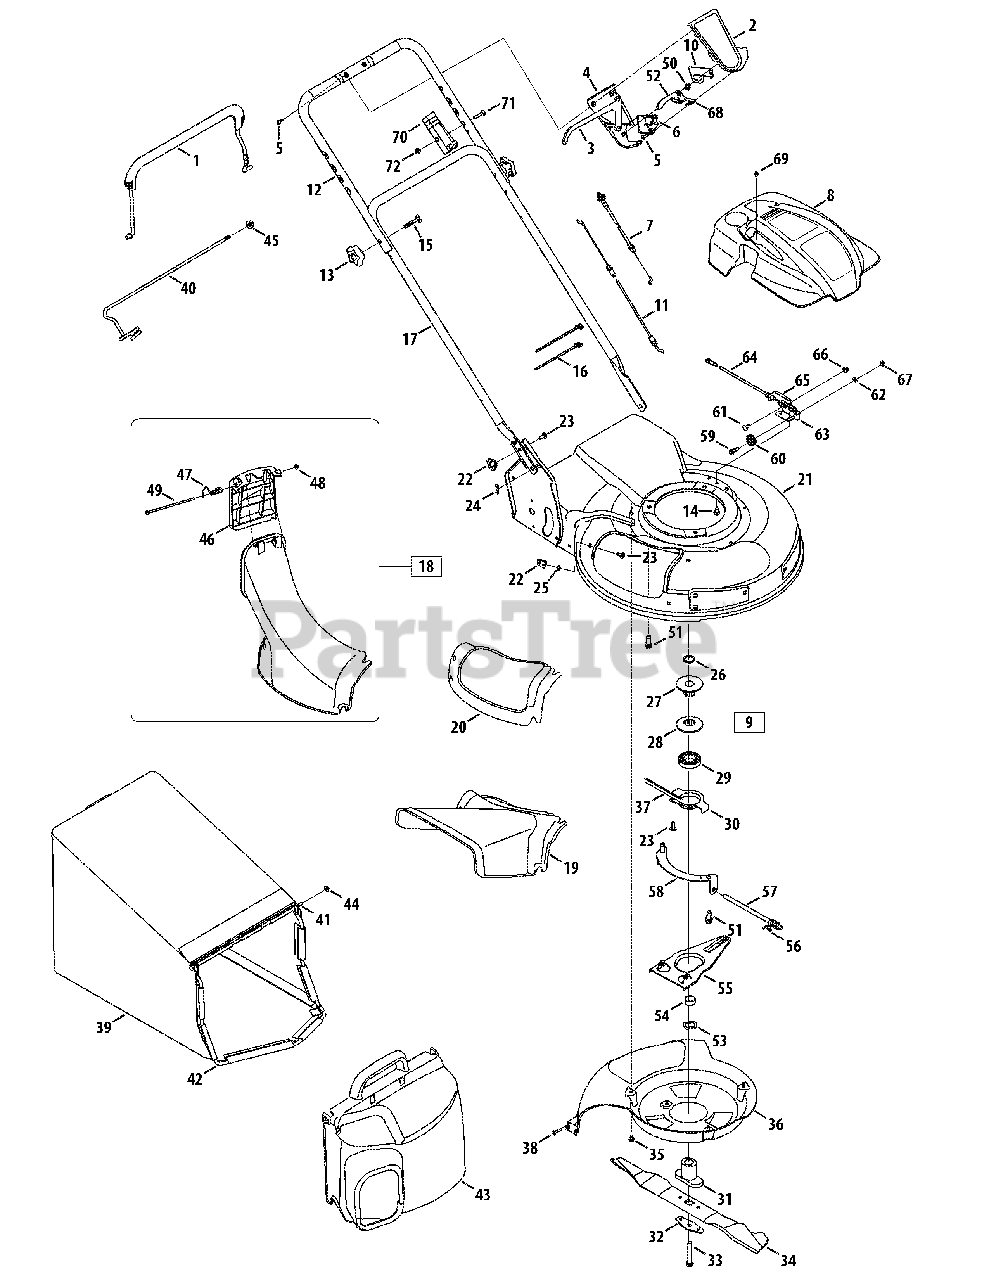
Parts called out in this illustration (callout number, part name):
1	Blade Control
2	Upper Control Housing
3	Drive Control
4	Lower Control Housing
5	C Sunk Tap Screw, #10 x .75 Lg
6	Cable Mounting Cap†
7	Drive Cable
8	Engine Shroud
9	Pulley Assembly
10	6 Spd. Rack Cable Bracket
11	Control Cable
14	Screw, 1/4-20 x .625
15	Carriage Bolt, 5/16-18 x 2.0
16	Cable Tie
18	Adapter Assembly
19	Side Discharge Chute
20	Mulch Cover
22	Wing Nut
23	Carriage Bolt, 1/4-20 x .75"
24	Cotter Pin
25	Push Nut, .25 x ID x .50 OD
26	Sleeve Spacer, .88ID x 1.13OD
27	Half Pulley: 2.62 OD
28	Half Pulley: 2.62 OD x 1.61
29	Ball Bearing
31	Blade Adapter
32	Blade Bell Support
33	Hex Bolt, 3/8-24 x 2.5
34	21" Mulching Blade
35	Screw, 1/4-20 x 3.75
36	Baffle
37	Belt, 3/8 x 39.24
38	Screw, 1/4-15 x .750
39	Grass Catcher
40	Support Rod w/ Rope Guide
41	Pivot Rod
42	Grass Catcher Frame
43	Grass Catcher Cover
44	Cap Nut
45	Flange Lock Nut, 5/16-18
46	Chute Door
47	Torsion Spring
49	Pivot Rod
50	Gear Insert
51	Sems Screw, 3/8-16 x 1.00
52	6 Speed Shift Lever
53	Wave Washer, 1.38 ID x.88 OD
54	Slve Spacer, .88 ID x 1.00 OD
57	Pivot Shaft
59	Shlder Screw, .375 ID x 1/4-14
60	Cable Roller
61	Carriage Screw, 1/4-20 x .62
62	Lock Washer, 1/4
63	Cable Mounting Bracket
64	6 Speed Cable
65	Cable Adjustment Bracket
66	Hex Nut 1/4-20
67	Hex Nut 1/4-28
68	Shift Lever Spring
69	Screw, #12-16 x 1.00
70	Control Housing
71	Screw, 1/4-20 x 1.310
72	Nut, Hexlk, 1/4-20
